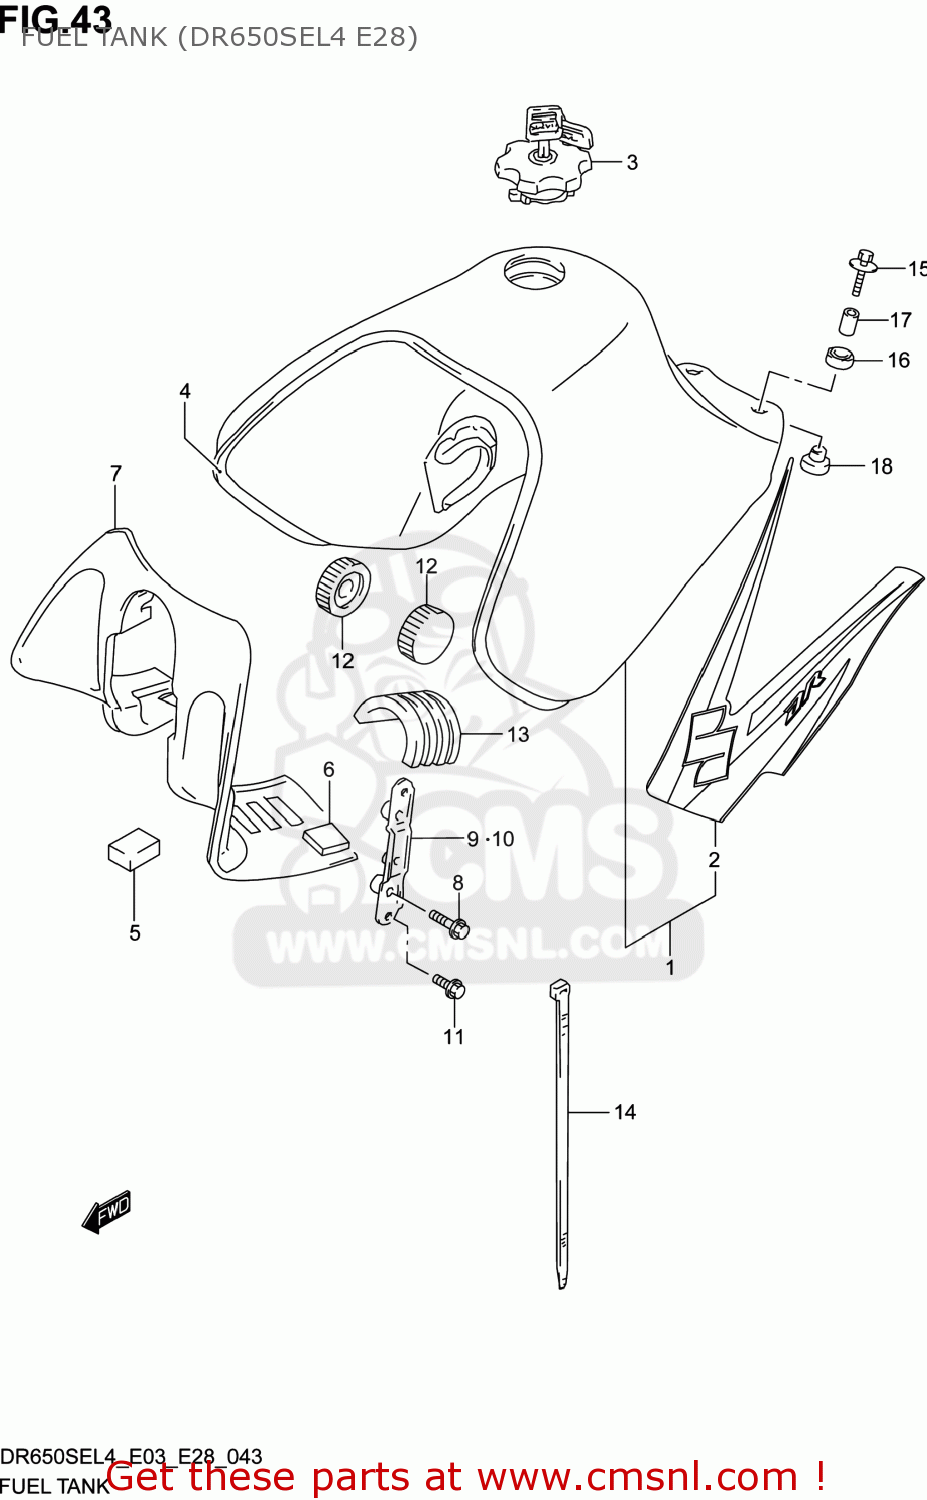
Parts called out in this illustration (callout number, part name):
1	TANK ASSY,FUEL(GRAY)
2	TAPE SET,FUEL TANK
3	CAP SET,FUEL TANK
4	MOLDING,FUEL TANK
5	CUSHION,HEAD LAMP HOUSING
6	CUSHION,OIL TANK UPR
7	COVER,FUEL TANK FR
8	BOLT(6X12)
9	BRACKET,FUEL TANK COVER,R
10	BRACKET,FUEL TANK COVER,L
11	BOLT
12	CUSHION,FUEL TANK FR
13	CUSHION,FUEL TANK UPR
14	CLAMP(L:250)
15	BOLT(6X30)
16	CUSHION
17	SPACER(6.5X9X18)
18	CUSHION
